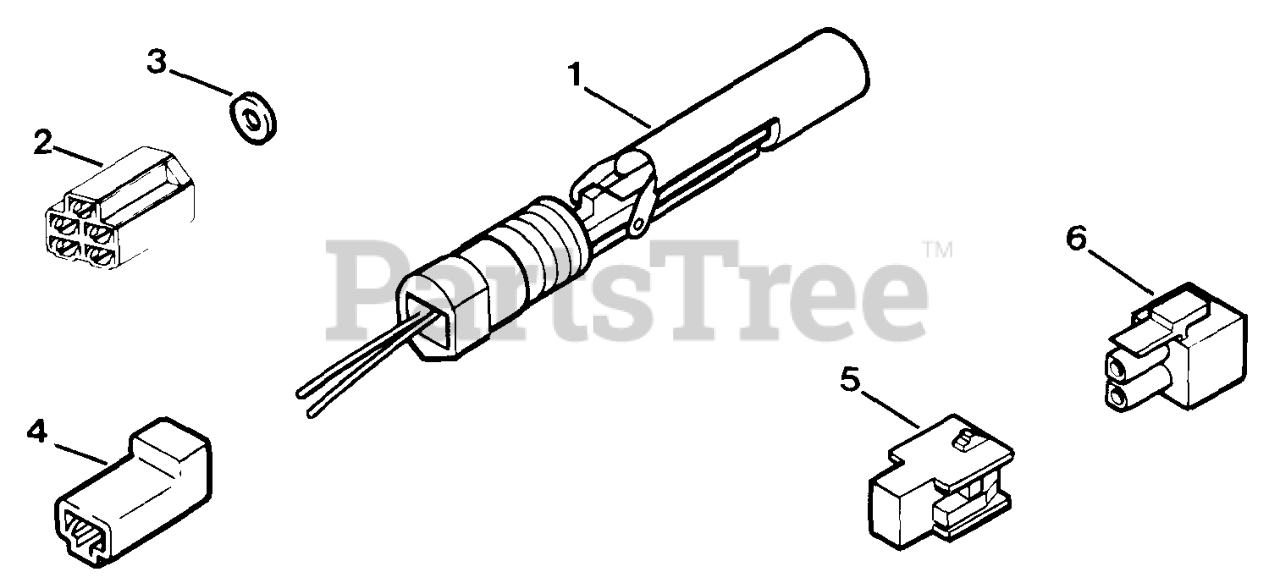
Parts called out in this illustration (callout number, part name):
1	KIT - USE 25 704 03
3	WASHER, FLAT 1/4" (O.D. 1/2")
4	CONNECTOR (1 CONTACT)
